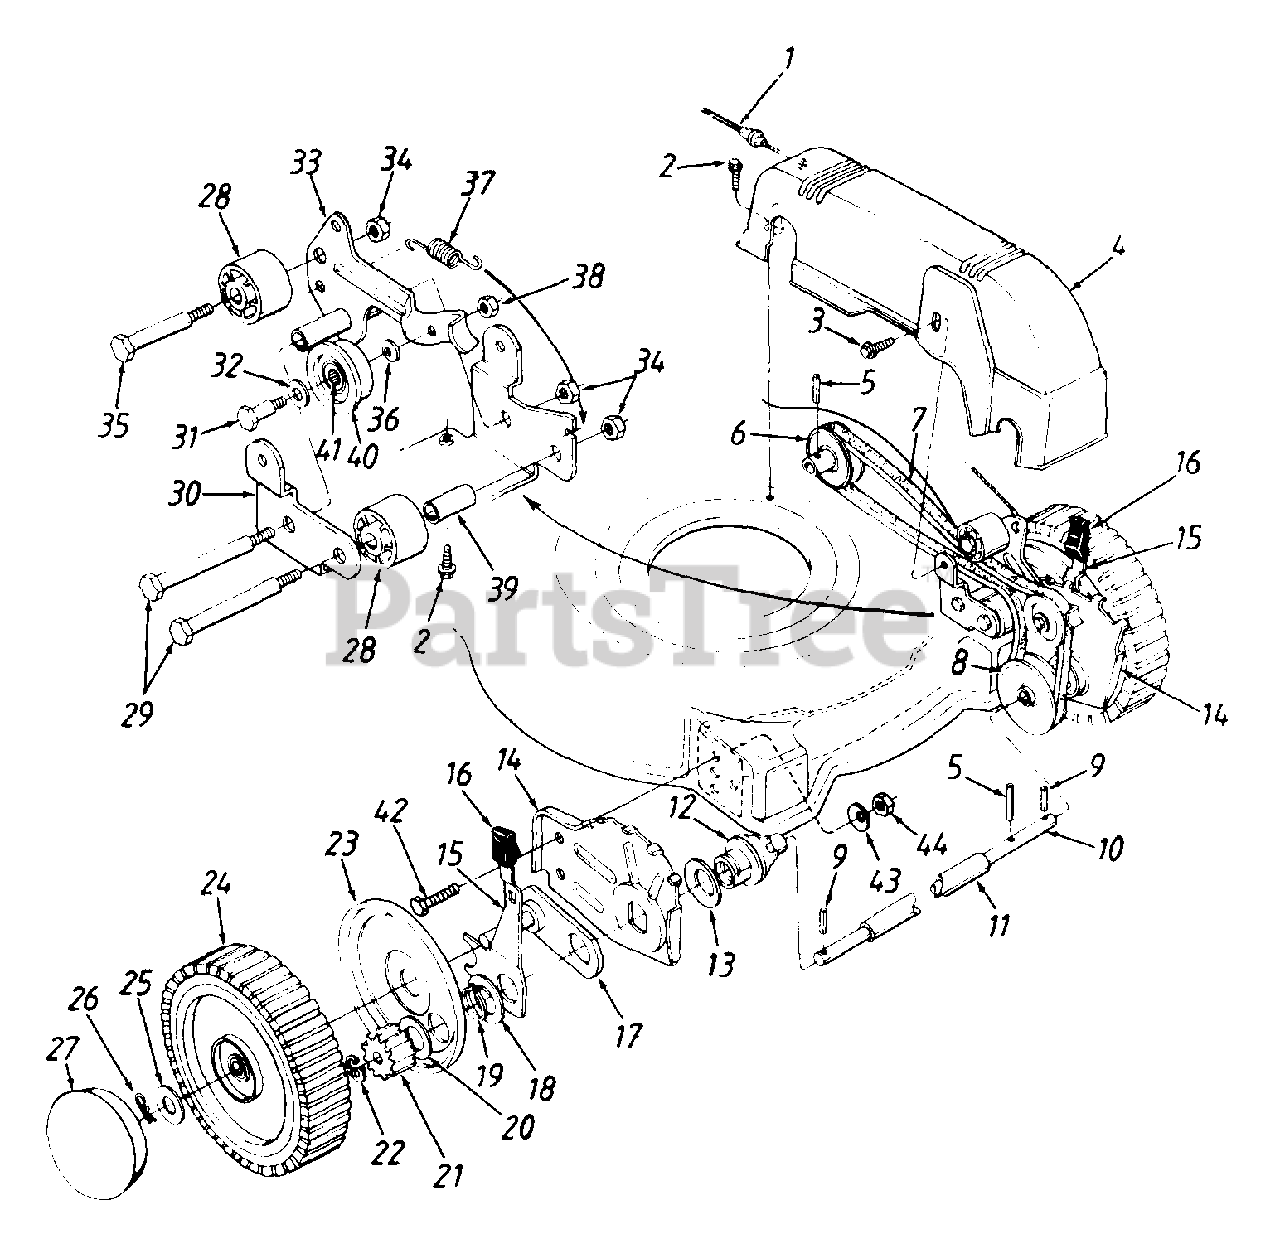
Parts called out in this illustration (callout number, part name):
1	Cable 44.75" Lg.
2	Hex Wash. Hd. TT-Tap Scr. 1/4-20 x .5" Lg.
3	Hex Wash. Hd. Tap Scr. 1/4-20 x .38" Lg.
4	Belt Cover
5	Spring Pin 3/16" Dia. x 1.25" Lg.
6	3/8" "V"-Pulley 2.75" O.D.
7	"V"-Belt
8	3/8" "V"-Pulley 2.44" O.D.
9	Spring Pin 3/16" Dia. x .875" Lg.
10	Front Axle
11	Axle Shroud
12	Front Bearing Ass'y.
13	Wave Wash. 1" I.D. x 1.5"
14	Height Adj. Plate - R.H.
15	Spring Lever - R.H.
16	Spring Lever Knob
17	Height Adj. Pivot Plate Ass'y.
18	DD Washer 1.5" O.D.
19	Snap Ring
21	14-T Spur Gear
22	E-Ring
23	Wheel Dust Cap
24	Front Wheel Ass'y.
25	Fl-Wash..531" I.D. x 1" O.D.
26	Hairpin Clip 5/16" Dia.
27	Hub Cap
28	Idler Ass'y.
29	Shld. Bolt .374" Dia. x 1.94"
32	Fl-Wash..39" I.D. x 1" O.D.
35	Shld. Bolt 3/8" Dia. x 1.16"
36	Bell-Wash..265" I.D. x .75" O.D.
37	Spring Extension 1.29" Lg.
38	Hex Nut 1/4-28 Thd.
39	Spacer 385" I.D x 625" O.D
40	Fl-Idler 1.5" O.D.
41	Needle Brg..375" I.D.
42	Bell-Wash..39" I.D. x 1.13" O.D.
44	Hex Nut 3/8-16 Thd.
